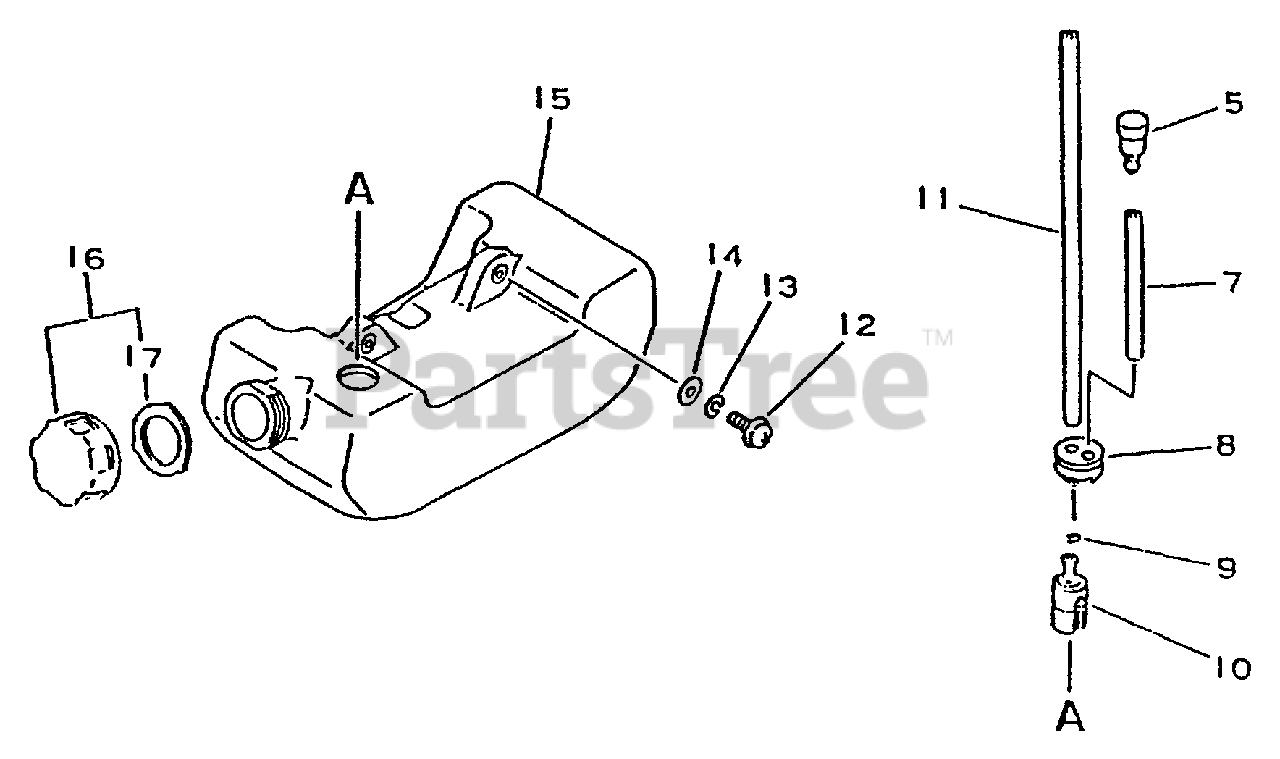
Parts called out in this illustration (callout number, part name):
5	VENT ASSY
7	PIPE
8	GROMMET, FUEL
9	CLIP 6 MM
10	FILTER, FUEL
11	PIPE, FUEL
12	SCREW 5×16
13	WASHER, SPRING 5
14	WASHER 5.5×12×0.8
15	TANK, FUEL
16	CAP ASSY
17	GASKET, FUEL CAP
